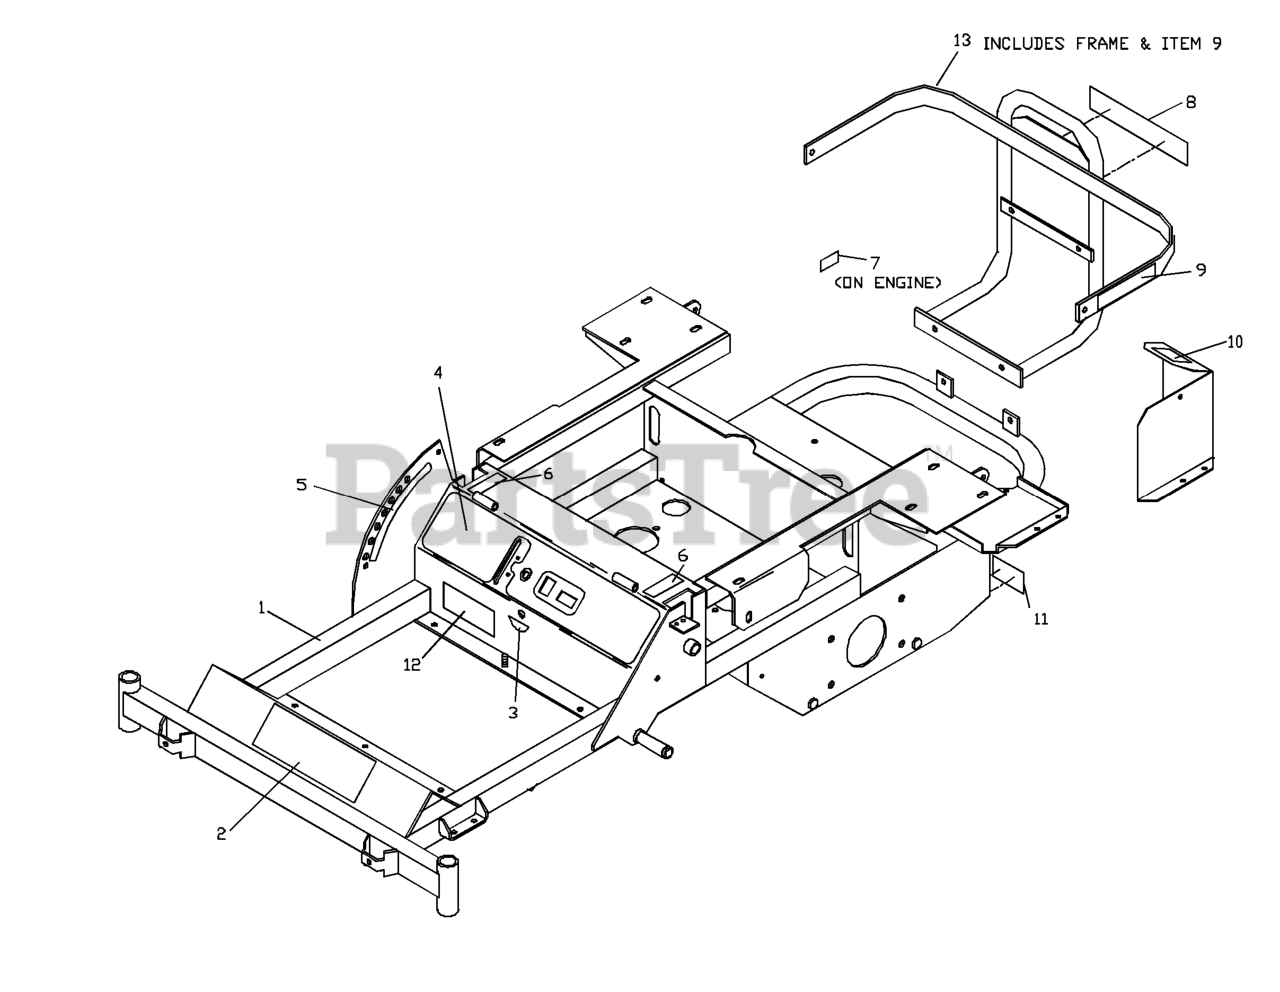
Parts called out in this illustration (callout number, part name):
1	FRAME W/DECALS KOHLER
1	FRAME W/DECALS KAWASAKI
2	DECAL, HUSQVARNA 15.5"
3	DECAL, FUEL VALVE
4	CONSOLE DECAL
4	DECAL, CONSOLE KOHLE
5	DECAL, LOCATOR
6	DECAL, MOTION CONTROL
7	DECAL, EXHAUST
8	DECAL, HUSQVARNA LOGO 9.25"
9	DECAL, BATTERY
10	DECAL, PROP. 65
11	DECAL, DANGER
12	DECAL, NASCAR
13	ENGINE GUARD W/DECAL
